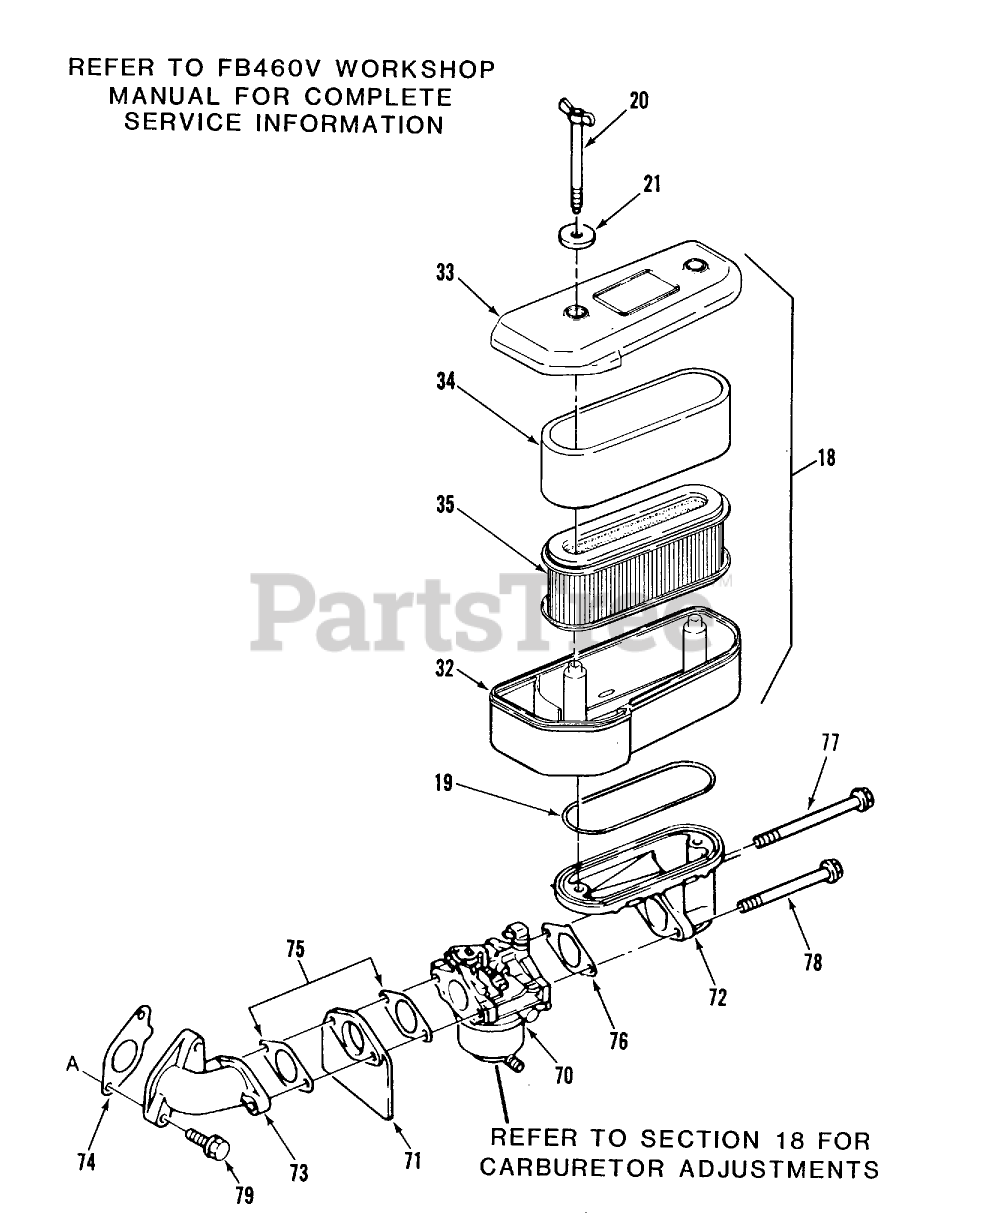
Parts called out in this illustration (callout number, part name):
18	Air Filter Assy (includes items 32, 33, 34 35)
32	Air Filter Case
33	CAP-Air Filter
34	Element
35	Element
70	Carburetor Assy-see section 9-6 for parts breakdown
71	Insulator
72	Pipe-Intake
73	Pipe-Intake
79	Bolt-Flanged (8X25)
